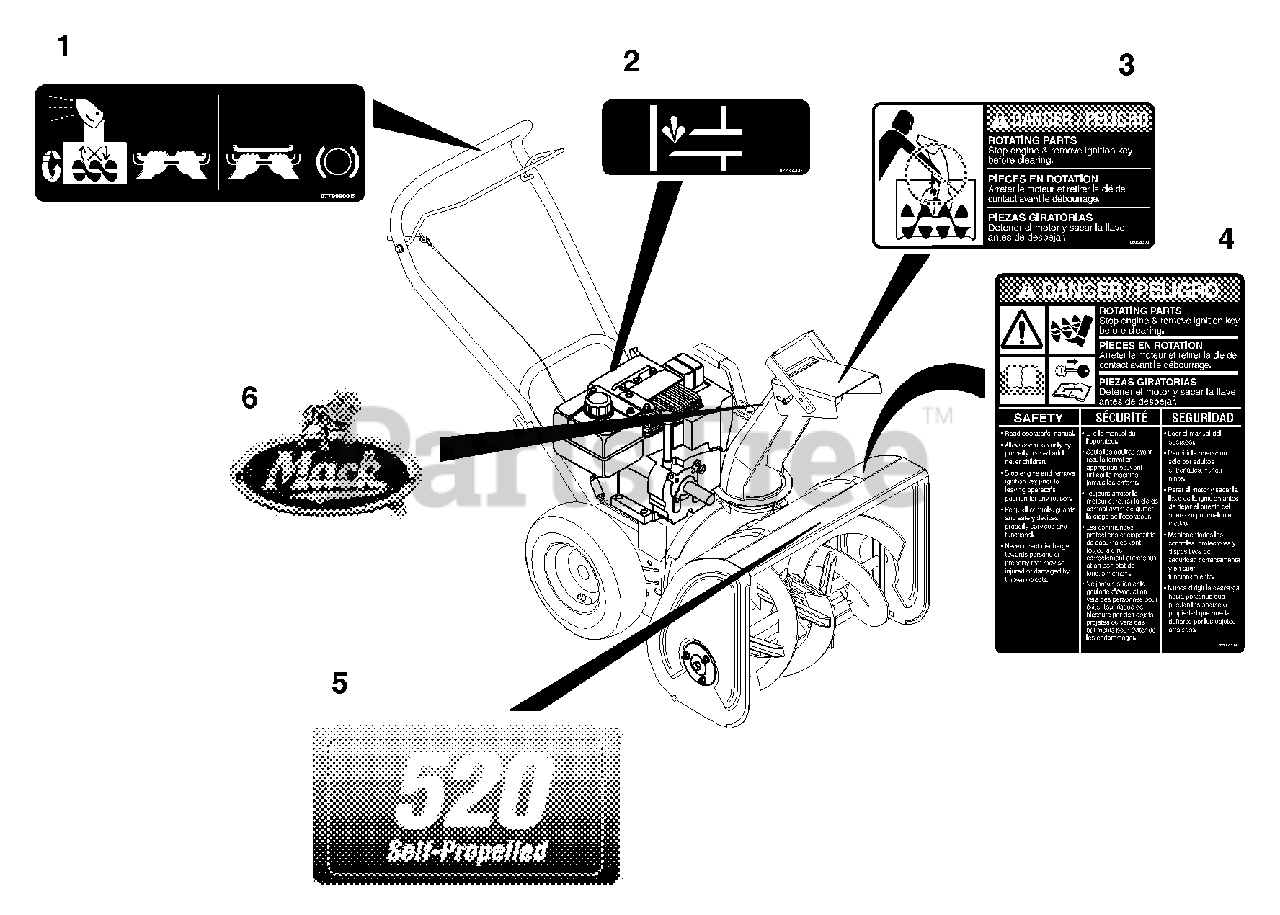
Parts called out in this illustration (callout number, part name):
1	HANDLEBAR DECAL
2	DECAL, PRIMER "TECUMSEH'S"
3	DECAL, DANGER - ROT. PARTS
4	DECAL, DANGER
5	DECAL, HOUSING - 520 MACK
6	DECAL - MACK ST LOGO
